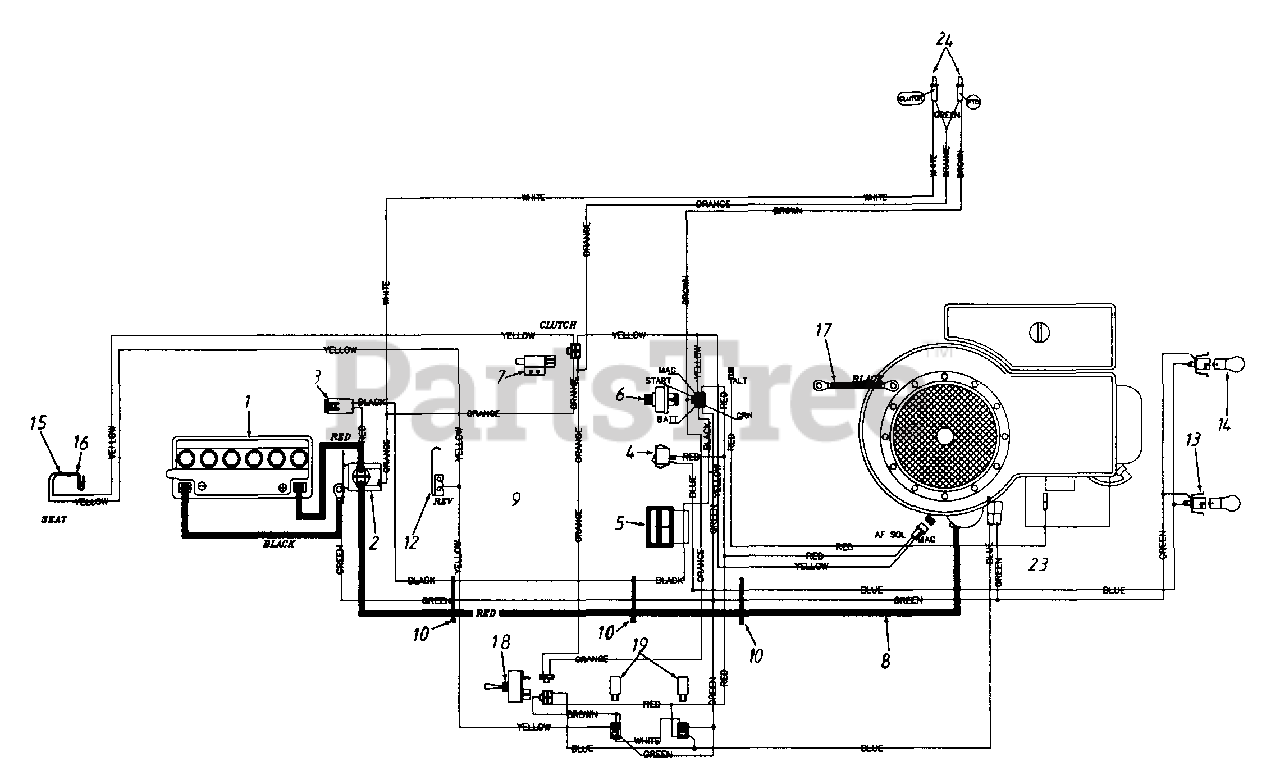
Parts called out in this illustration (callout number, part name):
1	Battery
2	Solenoid
3	Fuse
4	Light Switch
5	Ammeter
6	Ignition Switch
7	Clutch Safety Switch
8	Electric Wire
9	Wire Harness
10	Cable Tie
12	Reverse Safety Switch
13	Headlight Socket
14	Bulb
15	Seat Safety Switch
16	Seat Safety Switch
17	Electric Wire
18	Safety Switch (PTO)
19	Relay
23	Electric Clutch
24	Bulb
